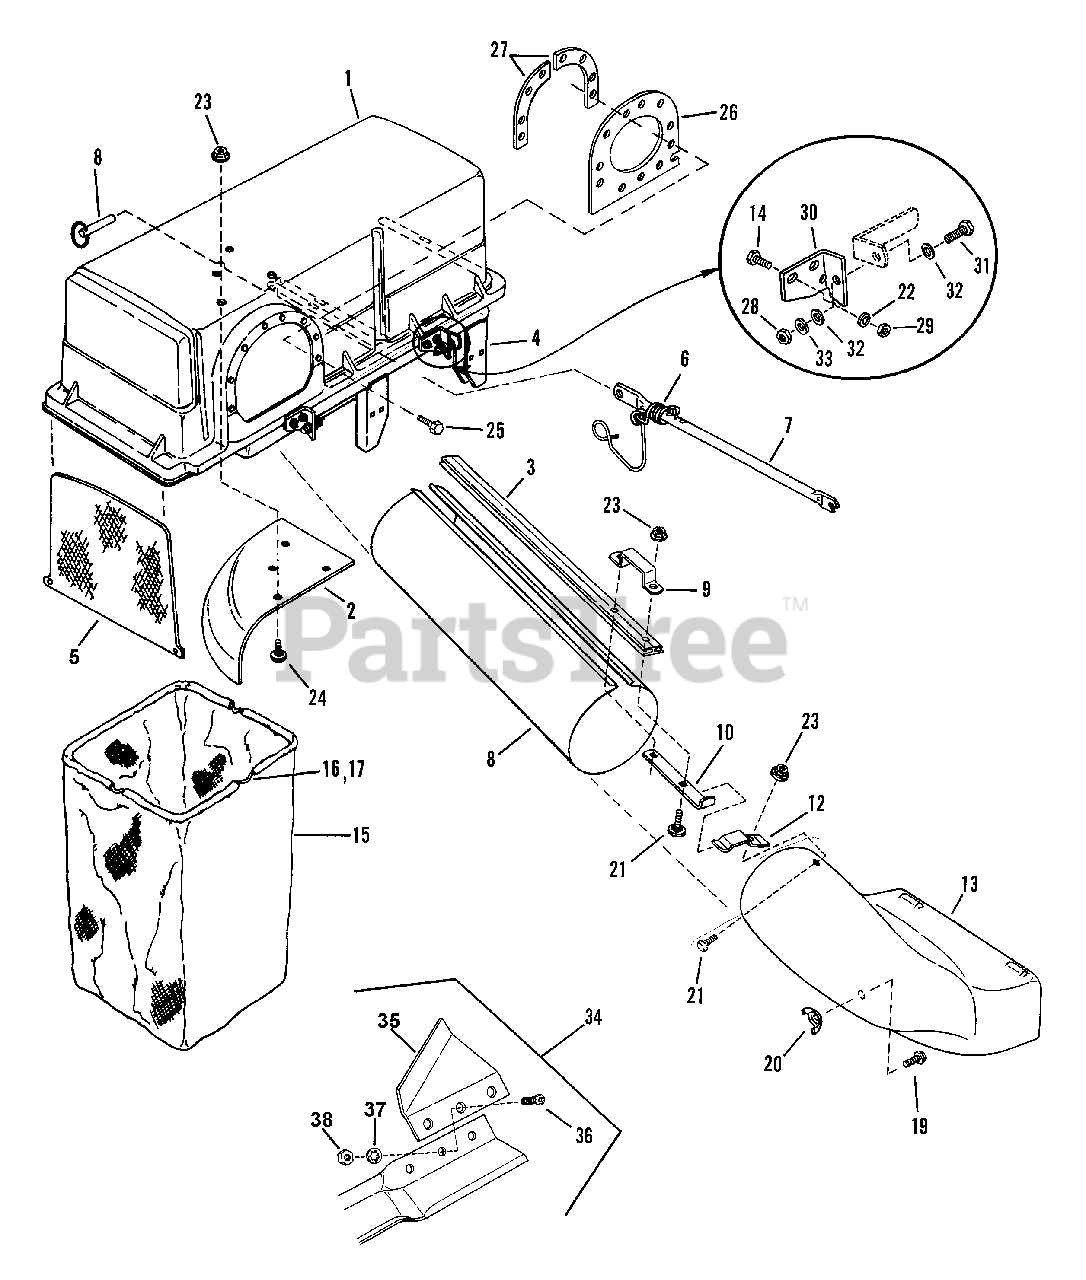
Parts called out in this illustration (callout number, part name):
1	ASSEMBLY, Cover
2	SECTOR, (Inside Top Baffle)
3	RIB, Grass Tube
4	ASSEMBLY, Mounting
5	ASSEMBLY, Screen
6	ASSEMBLY, Spring & Hook
7	BRACE
8	TUBE, Grass (46")
9	HANDLE, Tube
10	BASE, Tube Handle
12	LATCH, Tube
13	ADAPTER, Deck
14	SCREW, 1/4-28x3/4" Hex Head Cap 4)
15	BAG, Grass Catcher
16	ROD, Bag Support
17	CONNECTOR, Rod
18	PIN, Quick Release
19	BOLT, 5/16-18x1" Short Neck Carriage
20	NUT, 5/16-18 Wing
21	BOLT, 1/4-20x5/8" Flat Head Carriage
22	WASHER, 1/4 Internal Tooth Lock
23	NUT, 1/4-20 Hex Flange Lock
24	BOLT, 1/4-20x 1/2" Short Neck Carriage
25	SCREW, #10-24x1/2" Self-Tapping
26	SEAL, Cover
27	CLAMP, Seal
28	NUT, 5/16-24 Hex Center Lock
29	NUT, 1/4-28 Hex
30	HINGE, Top
31	SCREW, 5/16-24x1" Hex Head Cap
32	WASHER, 5/16 Flat
33	WASHER, 5/16 Split Lock
34	KIT, Air Lift
35	LIFT, Air
36	SCREW, 5/16-24x21/32" Cross Recess
37	WASHER, 5/16 Internal Tooth Lock
38	NUT, 5/16-24 Hex
39	Grass Bag Assembly
